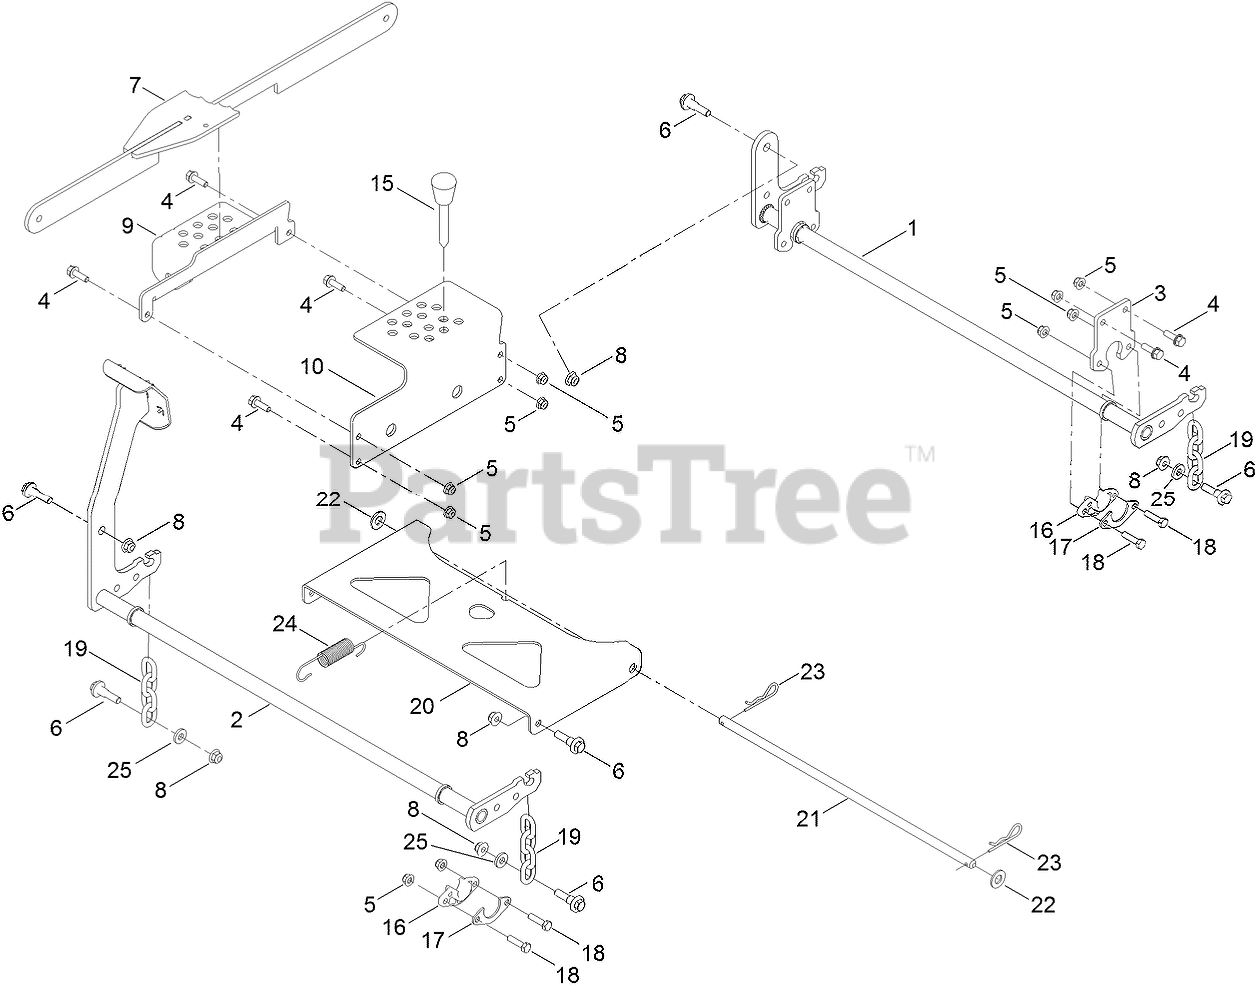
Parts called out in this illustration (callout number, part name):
1	PIVOT-REAR
2	PIVOT-FRONT
4	SCREW-HHF
5	NUT-HF, NI
6	BOLT-SHOULDER
7	LIFT LINK ASM
8	NUT-HF, NI
9	PLATE-HOC, LOWER
10	PLATE-HOC, UPPER
15	HOC PIN ASM
16	BEARING-FLANGE
17	GUSSET-DECK LIFT
18	SCREW-HH
19	CHAIN-DECKLIFT, 4-LINK
20	PAN-PIVOT, DECK
21	ROD-PIVOT, DECK
22	WASHER-FLAT
23	PIN-COTTER
24	SPRING-EXTENSION
25	SPACER-HUB, BLOWER
